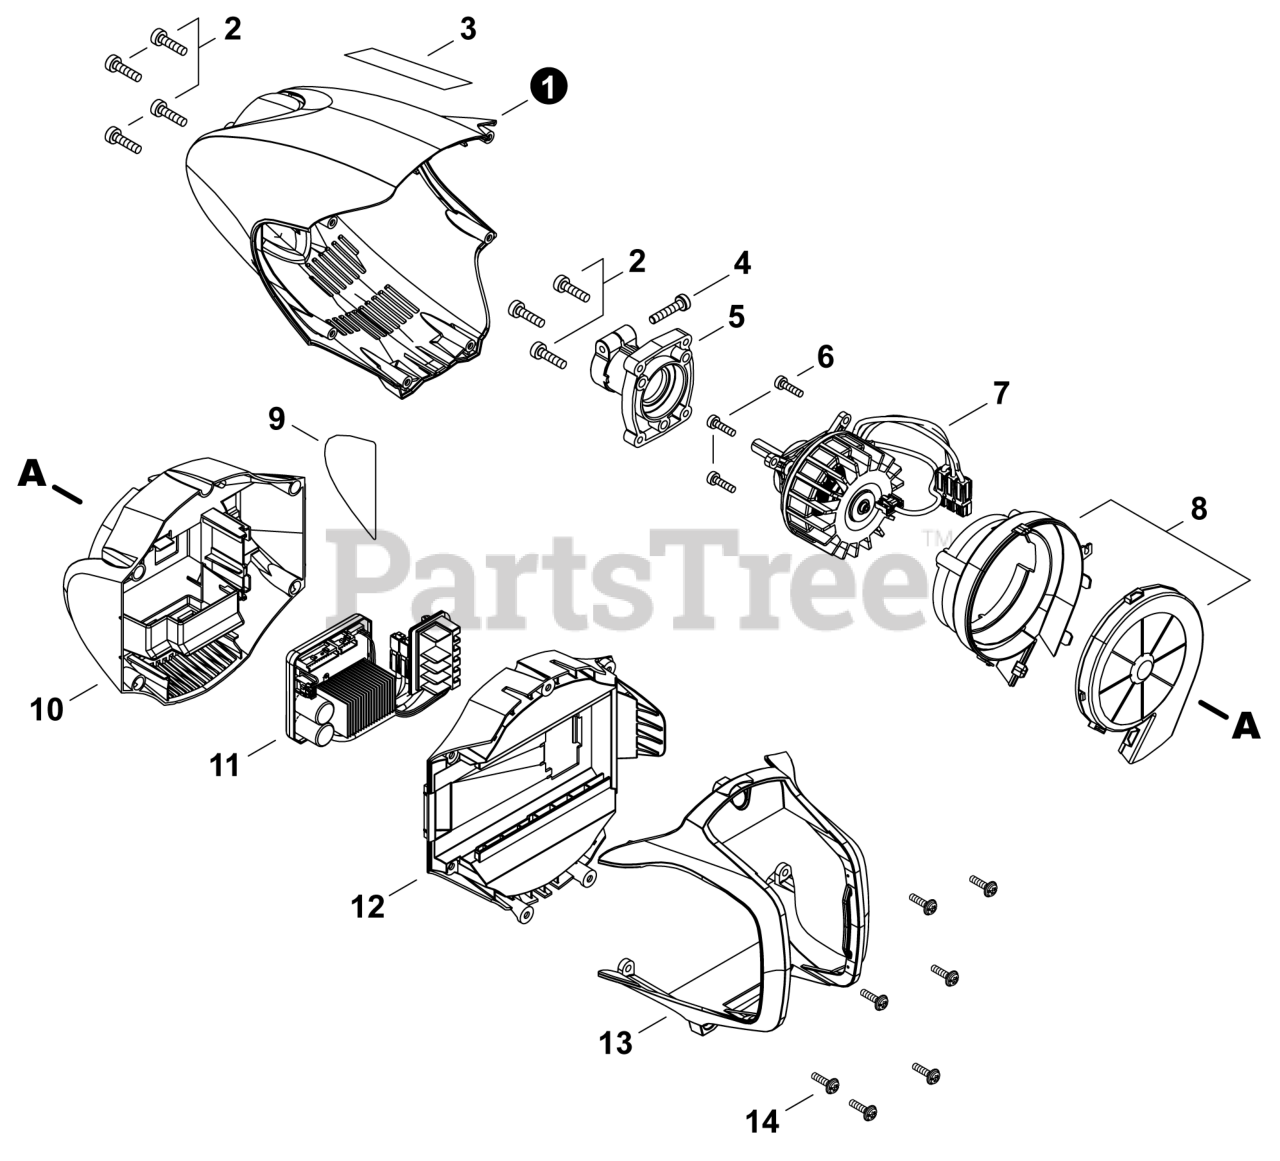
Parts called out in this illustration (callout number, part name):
1	COVER, MOTOR
2	BOLT, TORX 5x20
3	LABEL - ECHO
4	BOLT, TORX 5x25
5	HOLDER, MAIN PIPE
6	BOLT, TORX 4x16
7	MOTOR ASSY
8	CASE ASSY, FAN
9	LABEL - MODEL DPE-2600
10	DUCT, AIR
11	CONTROL BOARD ASSY
12	HOLDER, BATTERY
13	COVER, BATTERY
14	BOLT, TORX 4x16
